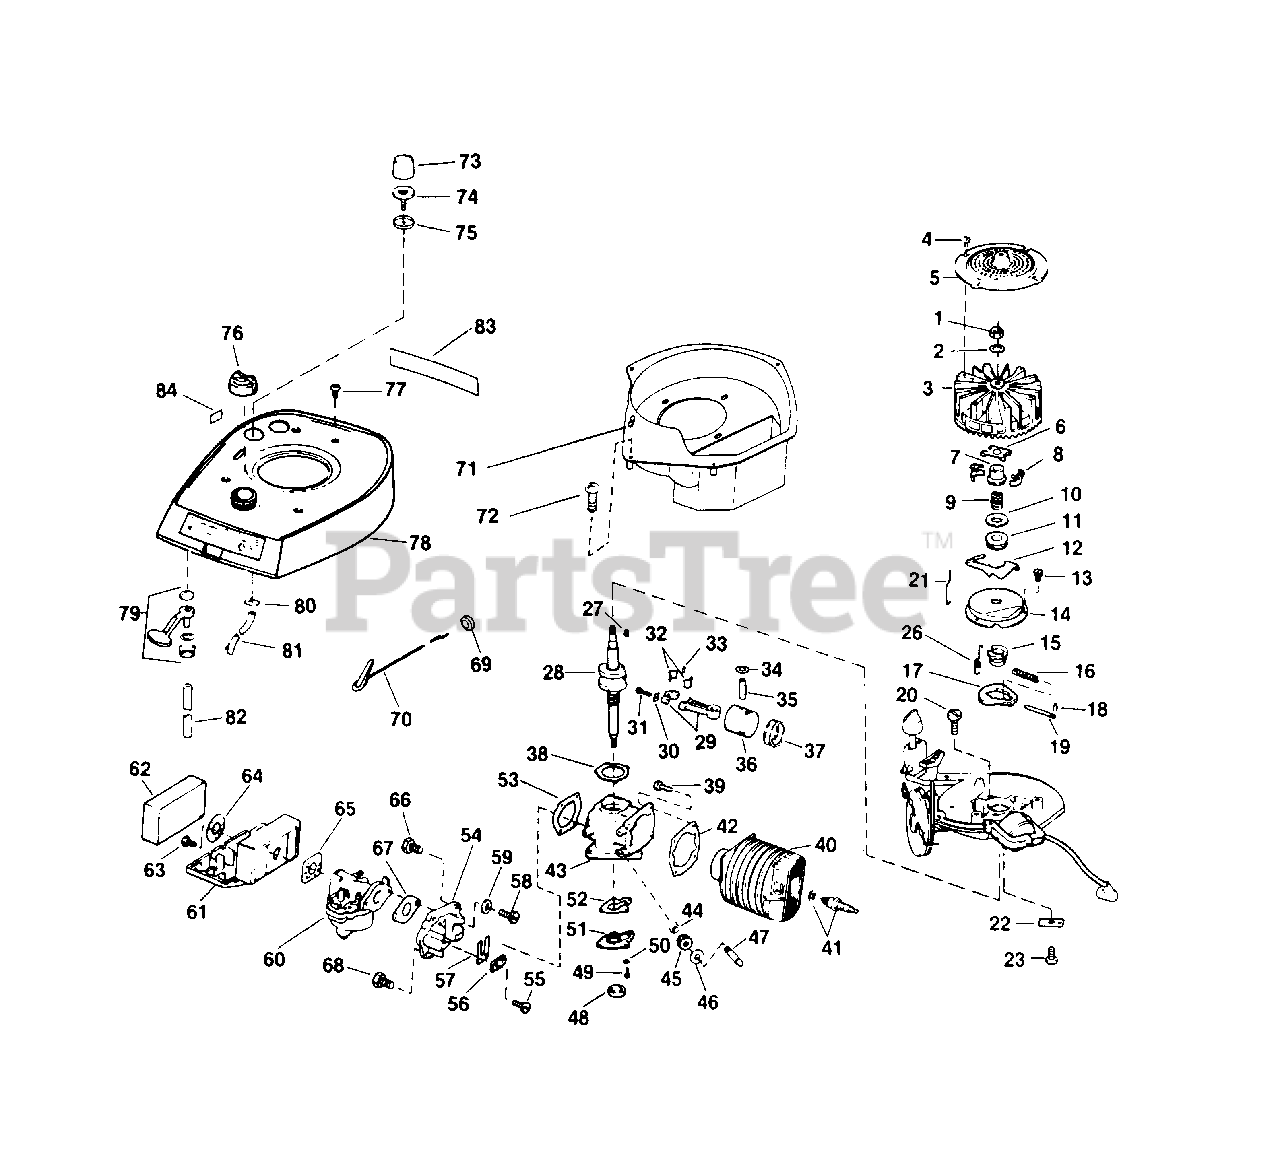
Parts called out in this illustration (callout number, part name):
1	Nut-Flywheel
2	Lockwasher-Flywheel
3	Flywheel & Screen Assy.
4	Screw-Thd. Cutting
5	Screen & Cup
6	Yoke-Governor
7	Collar-Governor
8	Weight-Governor
9	Spring-Governor
10	Thrust Washer
11	Collar-Thrust
12	Lever-Governor
13	Screw-Attaching Dust Cover
14	Dust Cover
15	Cam-Spark Advance
16	Spring-Spark Advance
17	Flywheel-Spark Adv.
18	Retainer-Spring
19	Pin-Spark Advance
20	Screw-Ann. Plate to Crankcase
21	Rod Governor
26	Spring-Variable Speed
27	Key-Crankshaft
28	Crankshaft
29	Connecting Rod Assy.
30	Lockplate
31	Screw-Connecting Rod
32	Liners-Connecting Rod
33	Needle Bearing Set
34	Retaining Ring
35	Wrist Pin
37	Ring Set
38	Gasket-Crankcase to Ann. Plate .005 in.
38	Gasket-Crankcase to Arm. Plate .010 in.
39	Screw-Cylinder to Crankcase
40	Cylinder & Sleeve Assy.
41	Spark Plug & Gasket
42	Gasket-Cylinder to Crankcase
43	Crankcase, Bearing & Seal
44	Seal, Driveshaft
46	Washer-Thrust
47	Driveshaft
48	Seal, Crankshaft
53	Gasket-Reed Plate
54	Reed Plate Assembly
55	Screw-Machine
56	Plate-Back-up
60	Carburetor
61	Case-Air Filter
62	Element
69	Grommet
70	Knob & Rod
71	Air Baffle Assy.
72	Screw-Baffle
73	Bulb-Primer
74	Base-Primer
75	Cap-Primer
76	Cap-Gas Tank
77	Screw-Cover
78	Cover-Engine
79	Fuel Shut-off
80	Fastener-Primer
81	Gas Line-Primer
82	Fuel Hose
83	Decal-Lawn-Boy
85	Decal RH
86	Decal LH
87	Clip-Speed Control
